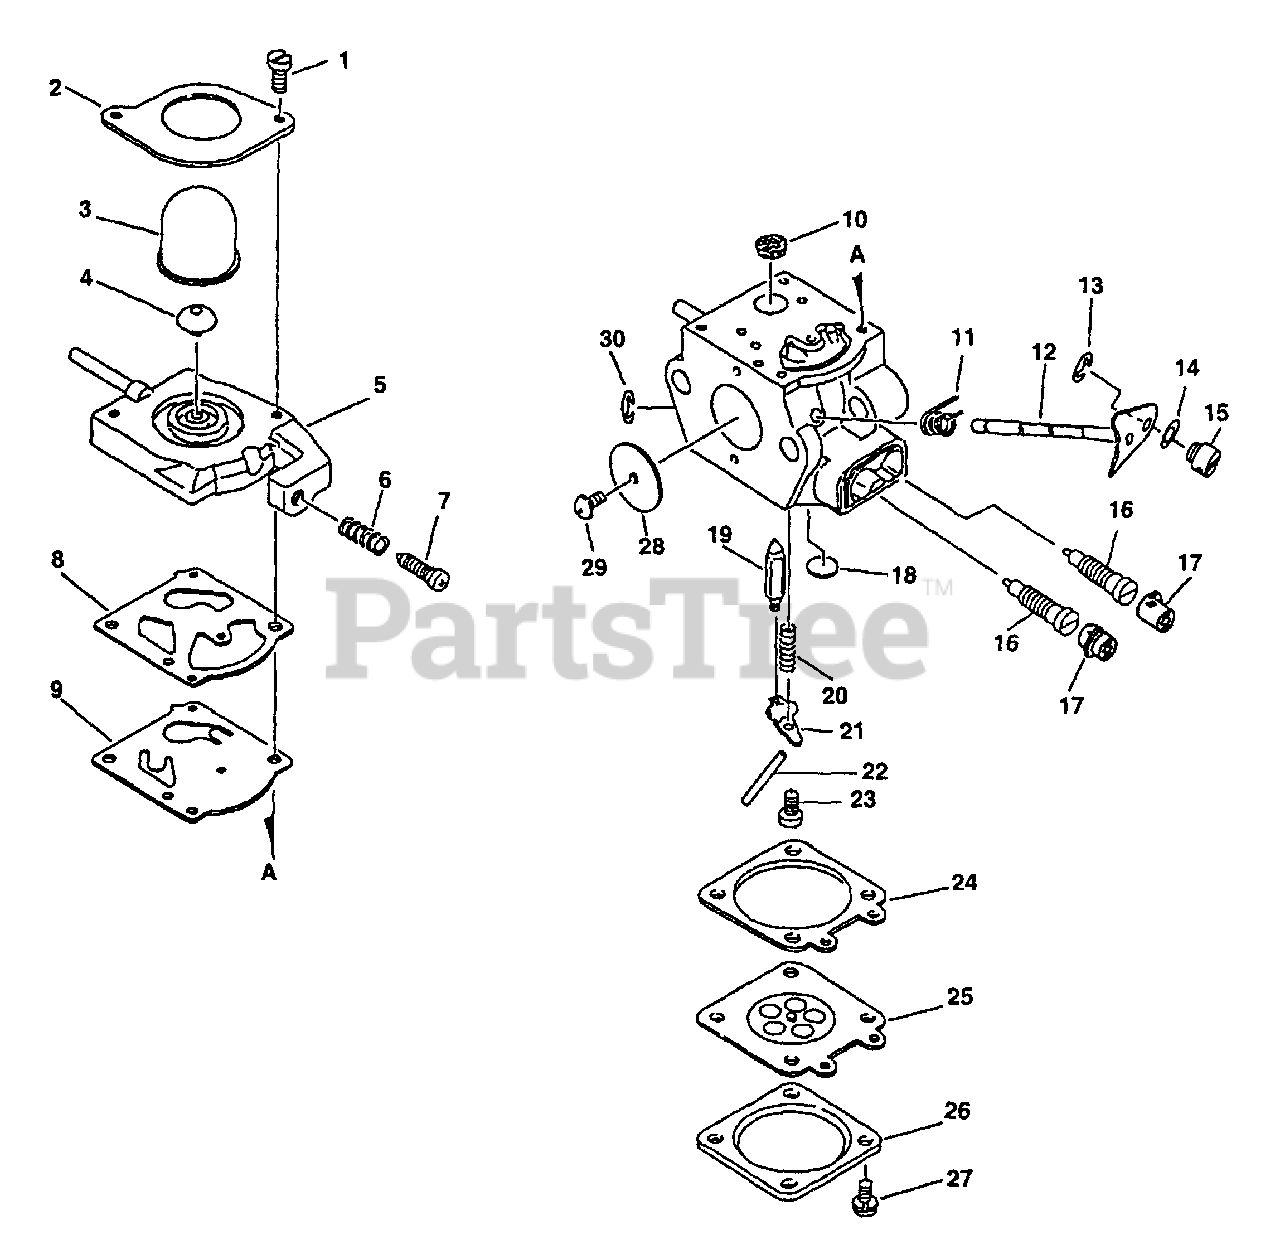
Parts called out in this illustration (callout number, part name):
1	SCREW, PUMP COVER
2	RETAINER, PURGE BULB
3	BULB, PURGE
4	VALVE, CHECK
5	BASE, PURGE
6	SPRING, IDLE ADJUST
7	SCREW, IDLE ADJUST
8	GASKET, PURGE
9	DIAPHRAGM, PURGE
10	STRAINER
11	SPRING, THROTTLE RETURN
12	SHAFT, THROTTLE
13	RING, RETAINING
16	NEEDLE - MIXTURE
17	CAP, LIMITER
18	PLUG, WELCH
19	VALVE, INLET NEEDLE
20	SPRING, METERING LEVER
21	LEVER, METERING
22	PIN, METERING LEVER
23	SCREW, METERING LEVER PIN
24	GASKET, METERING
25	DIAPHRAGM, METERING
26	COVER, METERING
27	SCREW
28	VALVE, THROTTLE
30	RING, RETAINING
